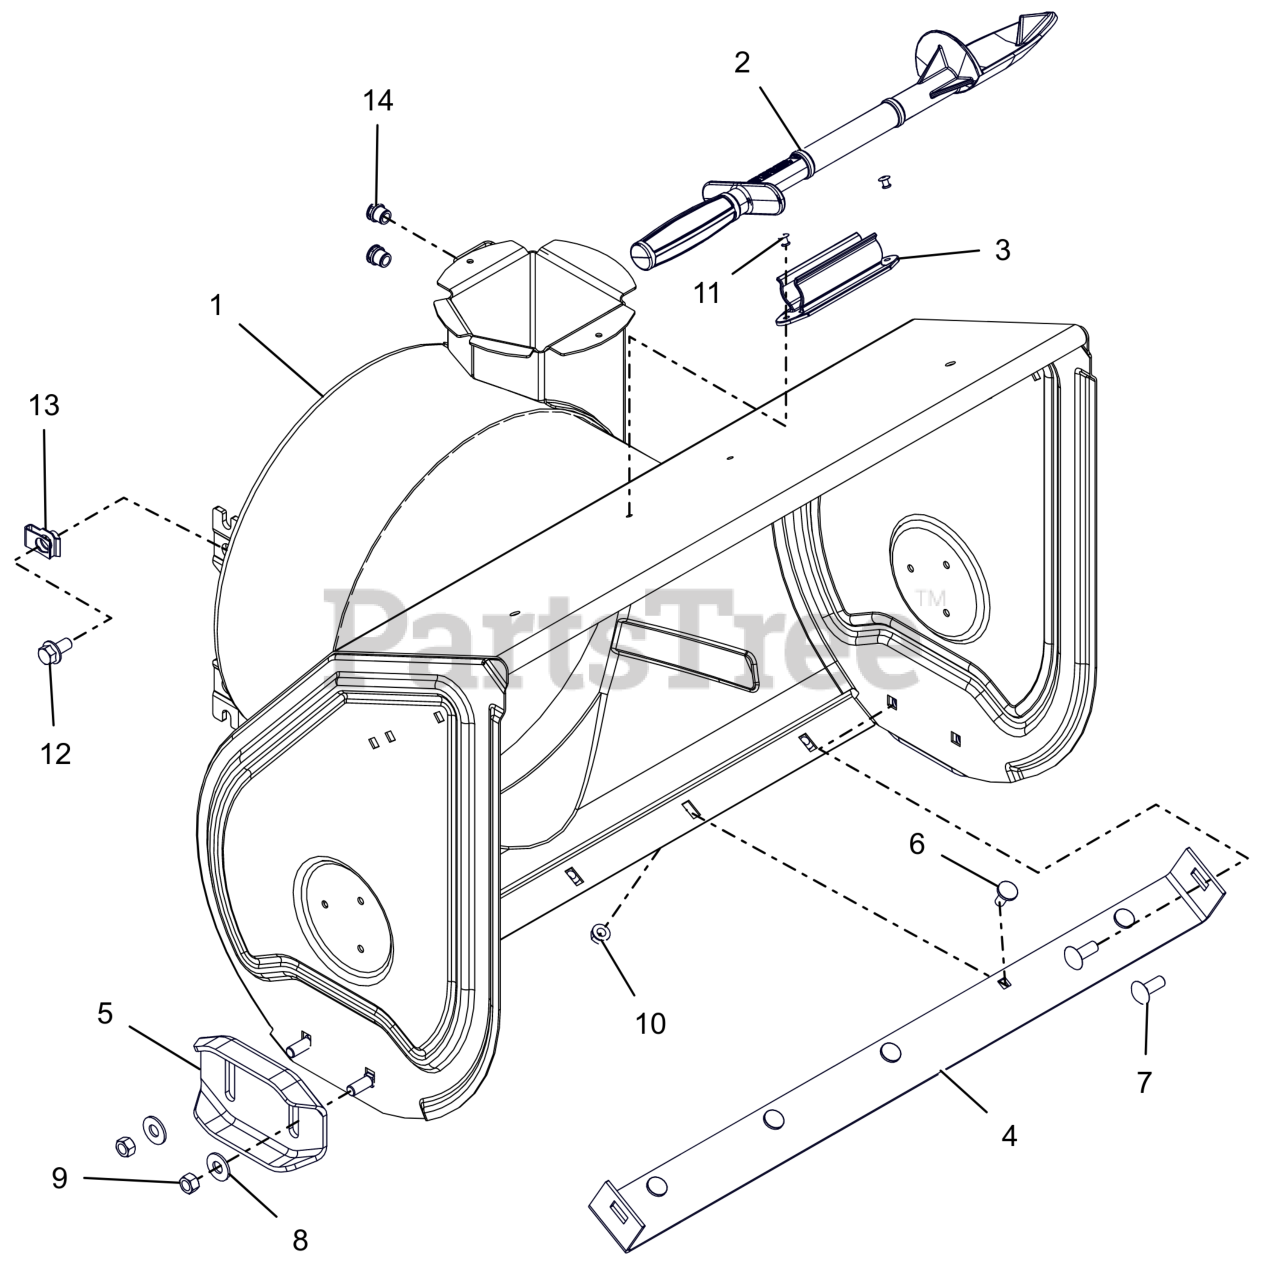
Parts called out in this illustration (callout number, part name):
1	BLOWER HOUSING W/DECAL 28"
2	DEVICE, SNOW CLEAN OUT
3	MOUNT, SNOW CLEAN OUT
4	BLADE, SCRAPER - 28"
5	SKID SHOE, REVERSIBLE - ORANGE
6	BOLT, MODIFIED HEAD CARRIAGE
7	BLT,RHSSN .38-16X1.00 G5 ZCC
8	WSHR,FLT .438X1.00X.083 ZCC
9	NUT-LK-CTR .38-16 ZC120
10	NUT-LK-TOP-FLG .312-18 GF ZCC
11	RVT, POP .1875 ZCC
13	NUT-RTNR .375-16X.37
14	NUT,THD,INSERT .38-16 ZC120
